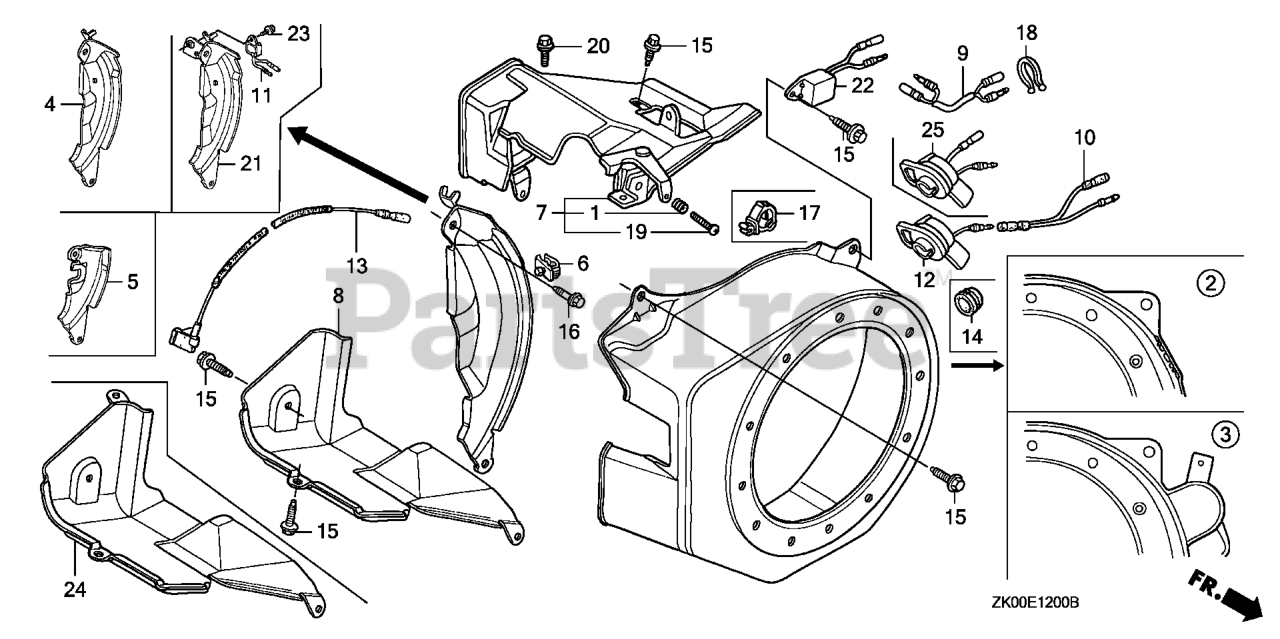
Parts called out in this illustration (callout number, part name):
2	COVER, FAN *NH246* (LOOSY GRAY)
2	COVER, FAN *R280* (POWER RED)
8	SHROUD
11	ALERT UNIT, OIL
13	WIRE, STOP SWITCH (370MM)
15	BOLT, FLANGE (6X12) (CT200)
16	BOLT, FLANGE (6X20) (CT200)
17	CLIP, HARNESS
21	PLATE, SIDE (OIL ALERT)
23	BOLT, FLANGE (6X8)
25	SWITCH ASSY., ENGINE STOP
